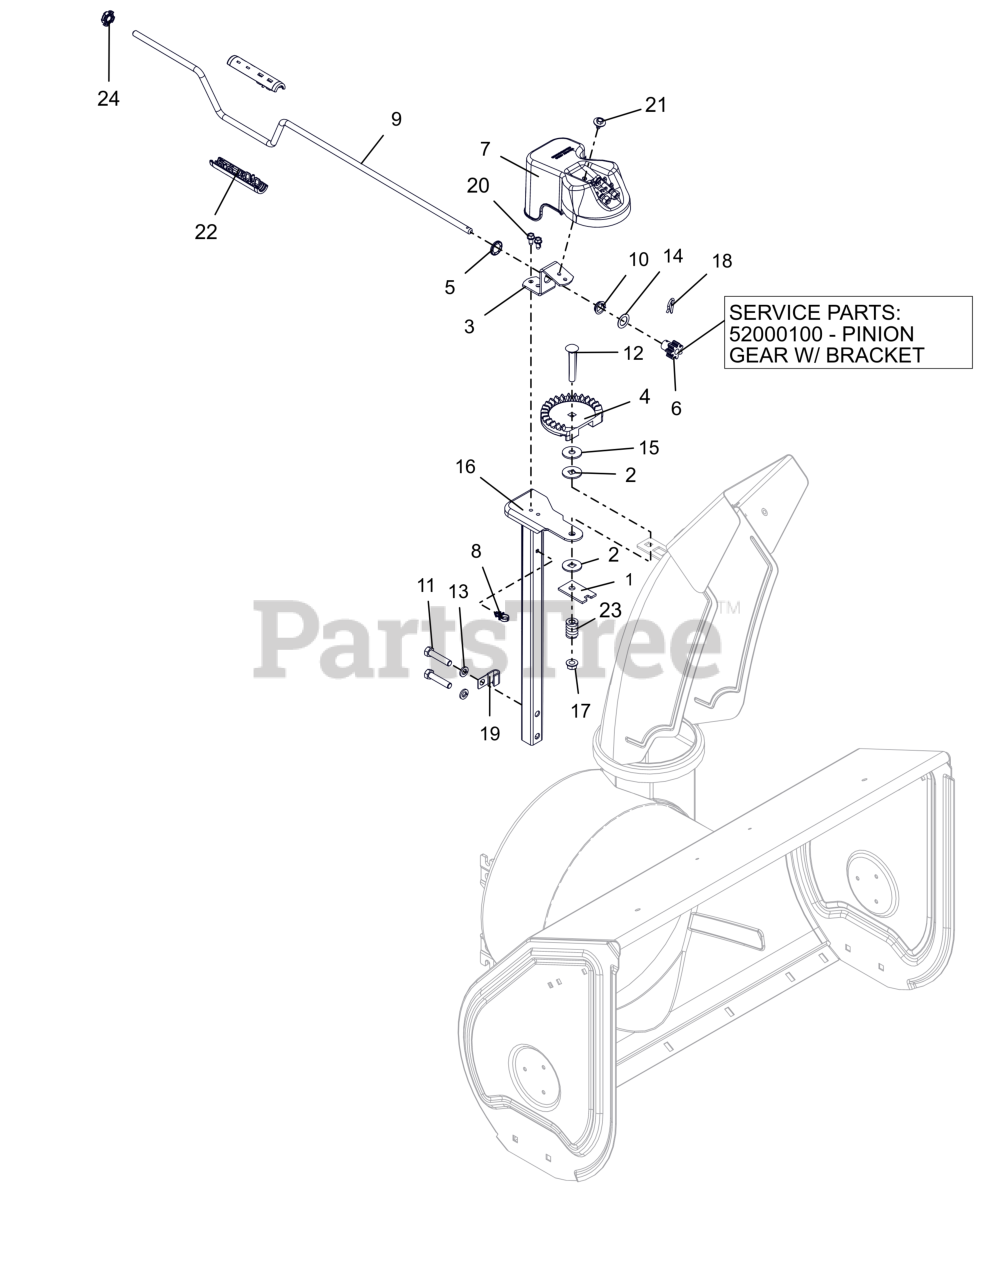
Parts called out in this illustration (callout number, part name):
1	PLATE, FRICTION
2	FRICTION WASHER
3	BRACKET, PINION GEAR
4	CHUTE GEAR
5	PUSHNUT .625
6	PINION GEAR - CHUTE
6	PINION GEAR W/BRACKET
7	GEAR COVER ASSY LG SHEAR BOLT
8	CLIP, CABLE GUIDE
9	ROD,CRANK - LGDASH DLX
10	BUSHING, POLYLINER-.63 SNAPIN
11	BLT, HEX .38-16X1.75 G5 ZCC
12	BLT,RHSN .38-16X2.50 G5 ZCC
13	WSHR,LK-REG .375X.094 ZCC
14	WSHR-THRST .625 X 1.0 X .03
15	WSHR FL STL .406X1.25X.10ZC120
16	PEDESTAL, CHUTE - CRANK
17	NUT-LK-TOP-FLG .38-16 ZC120
18	PIN, SPRING CLIP
19	J-CLAMP
20	SCR-TAP .25-20X.50 HWH ZCC
21	SCR, TAP .25-20X.50 LG HWH ZCC
22	KNOB,CHUTE CRANK-DELUXE
23	SG-COMP .187X.56X1.62
24	CRANK BUSHING, NYLON CHUTE BK
